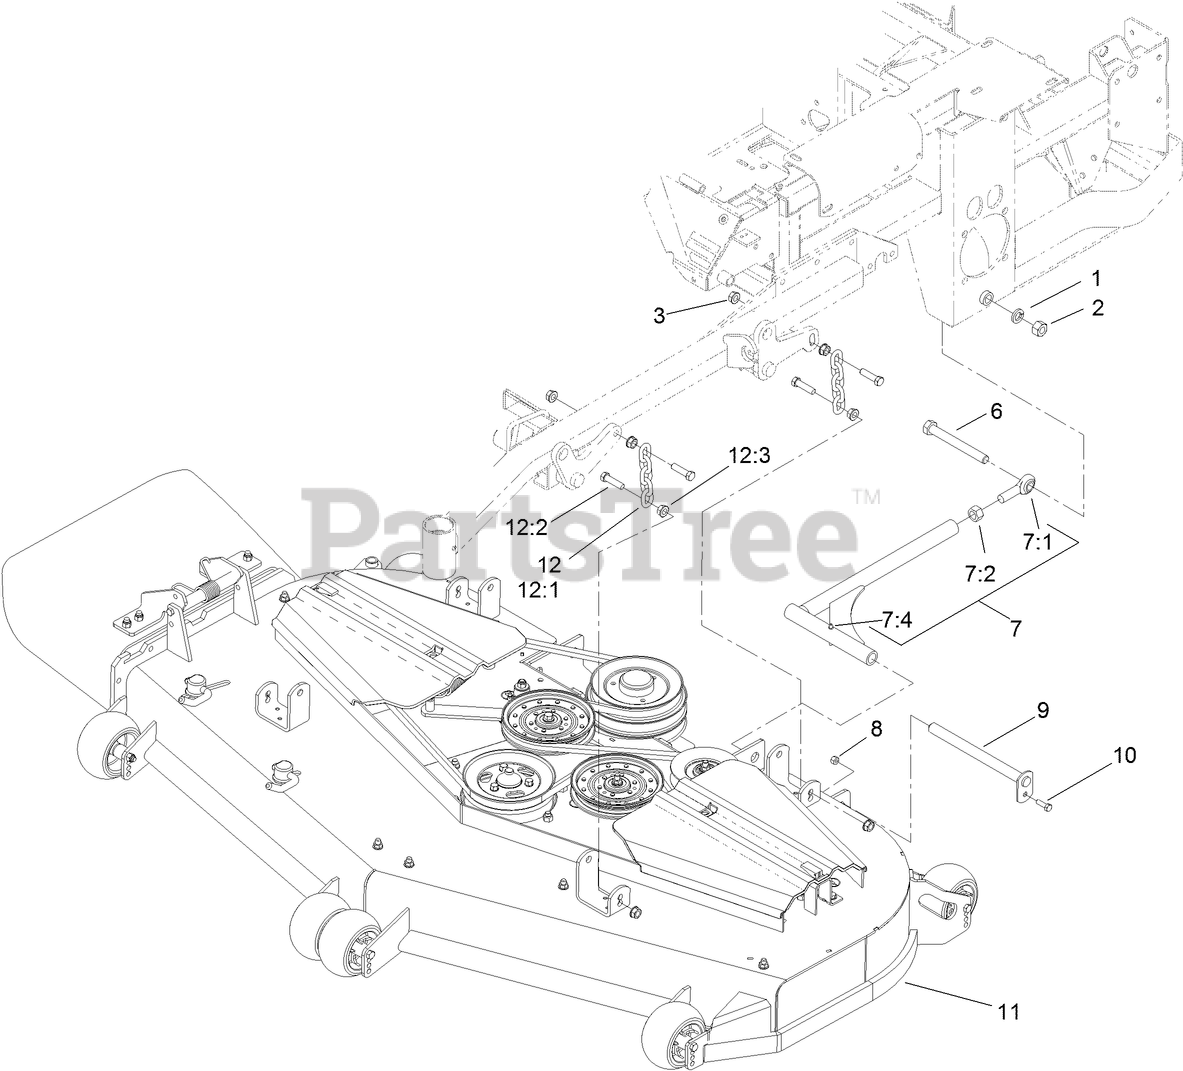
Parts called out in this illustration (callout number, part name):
1	WASHER-LOCK
2	NUT-HEX
3	NUT-HF
6	SCREW-HH
7	STRUT ASM
7:1	BALLJOINT-SPHERICAL
7:2	NUT-HEX
7:4	FITTING-GREASE
8	NUT-LOCK, NI
9	PIN-STRUT
10	SCREW-HH
11	DECK ASM
12	DECK CHAIN ASM
12:1	CHAIN-LIFT, DECK
12:2	SCREW-HH
12:3	NUT-HF
